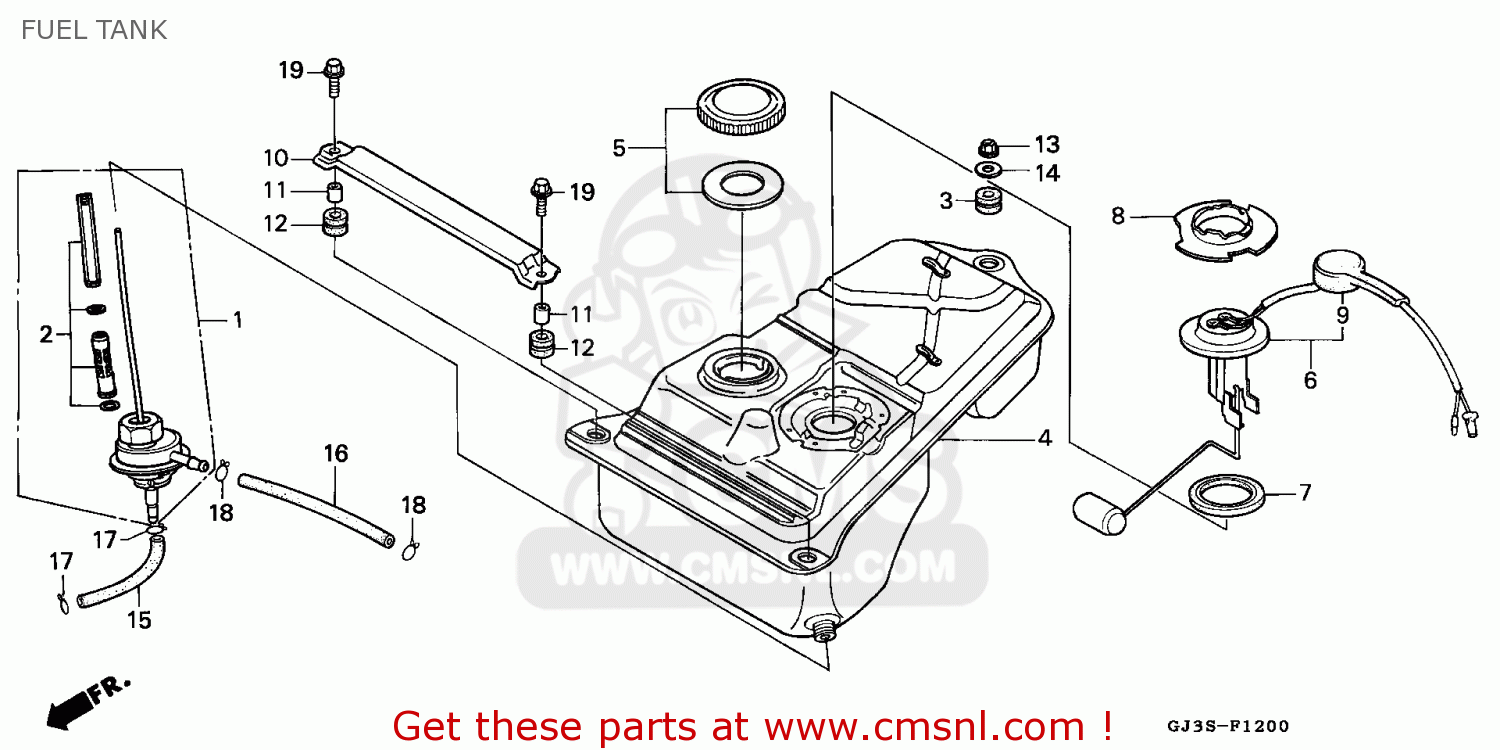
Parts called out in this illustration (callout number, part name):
1	AUTO,COCK.FUEL
2	SCREEN,FUEL STRAI
3	RUB,AIR/C MOUNT
4	FUEL TANK
5	CAP COMP. FUEL TANK
6	FUEL UNIT
7	PACKING,BASE
8	RET,FUEL UNIT
9	COV,FUEL UNIT
10	PL.A,FRAME CROSS
11	COLLAR,SEAT,MOUNT
12	RUBBER SEAT MOUNT
14	WASHER,PLAIN,6MM
15	TUBE,3.5X160
16	TUBE,FUEL 4.5X210
17	CLIP B7,TUBE
19	BOLT,FLANGE,6X22
